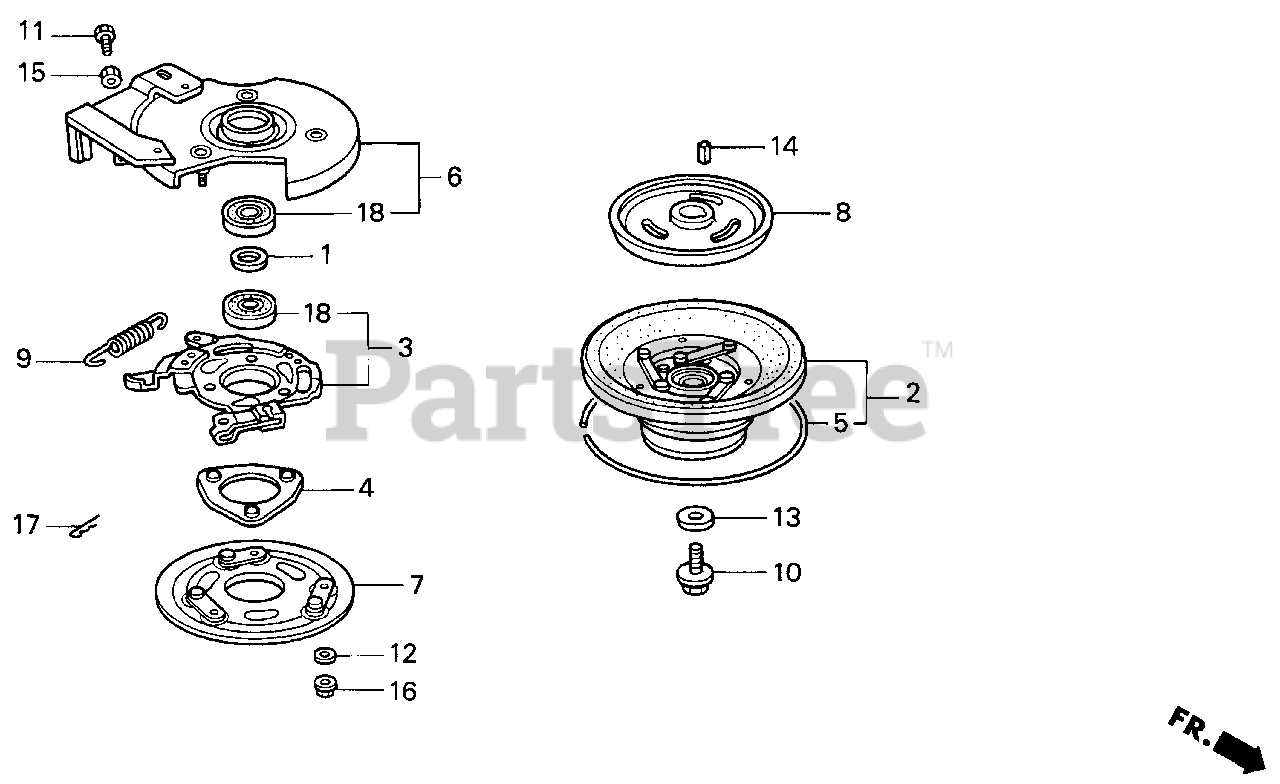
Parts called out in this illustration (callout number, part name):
1	WASHER, THRUST (25MM)
2	PULLEY ASSY., DRIVE
3	PLATE, BALL CONTROL
4	RETAINER, BALL
5	RING, P.T.O. CLUTCH
6	PLATE, BASE
7	PLATE, BRAKE
8	PLATE, DRIVE
9	SPRING, RETURN
10	BOLT, SPECIAL (8X30)
11	BOLT, ADJUSTING
12	WASHER (6MM)
12	WASHER (6X17X1.6)
13	WASHER, STEERING GEAR
14	KEY (7X7X18)
15	NUT, HEX. (8MM)
16	NUT, FLANGE (6MM)
17	PIN, LOCK (8MM)
18	BEARING, RADIAL BALL (6005UU)
